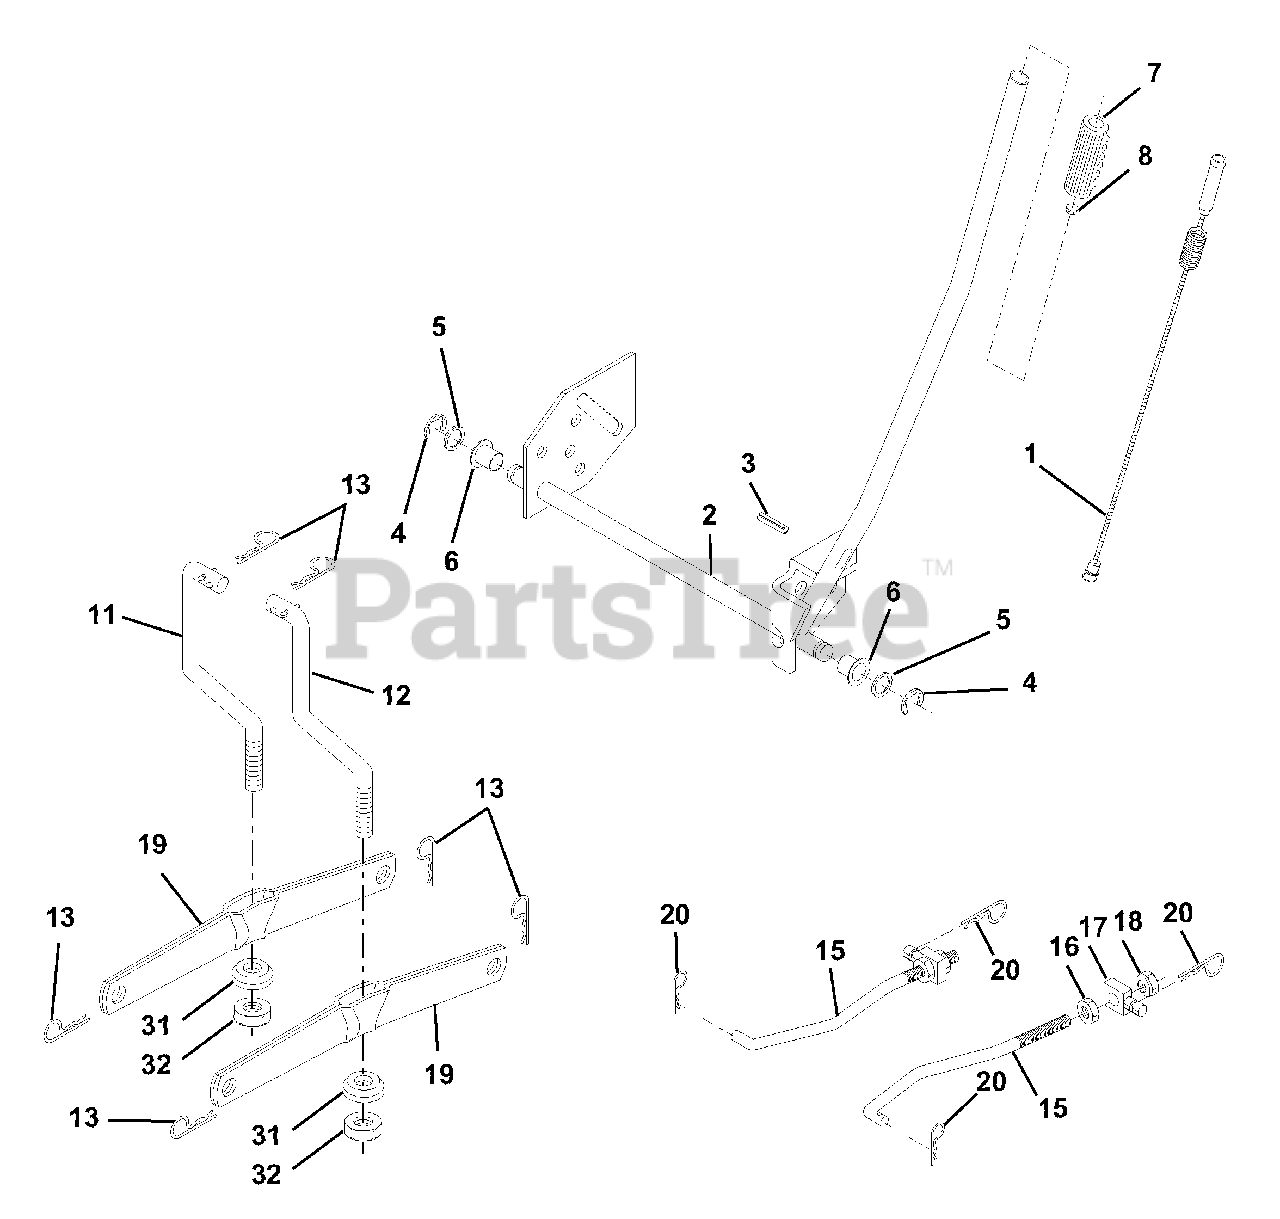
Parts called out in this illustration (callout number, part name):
1	Wire Asm Inner/Sprg w/Plunger
2	Shaft Asm Lift
3	Pin Groove
4	E Ring #5133-62
5	Washer 21/32 x 1 x 21 Ga.
6	Bearing Nylon
7	Grip Handle
8	Button Plunger
11	Link Lift Lh
12	Link Lift Rh
13	Retainer Spring
15	Link Front
16	Nut Jam Hex 1/2-13 Unc
17	Trunnion Blk Zinc
18	Nut Lock w/Wsh 1/2-13 Unc
19	Arm Suspension Rear
20	Retainer Spring
31	Bearing Pvt Lift Spherical
32	Nut Crownlock 3/8-24
